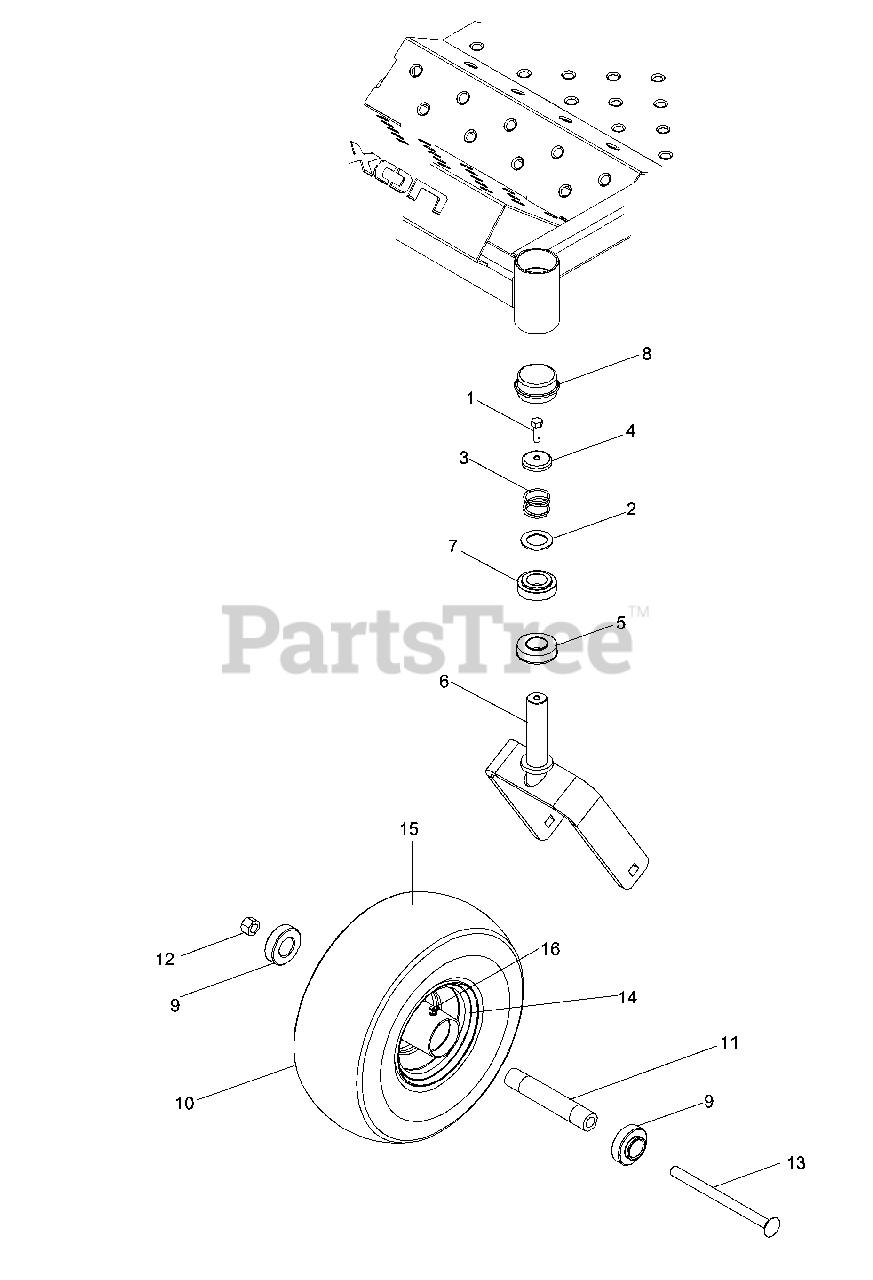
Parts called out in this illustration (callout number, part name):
1	5/16-18X1 HHB G5W/NY
2	WASHER, 1.025 ID X 1.64
3	SPRING, CASTER
4	CASTER.PLUG
5	BEARING
6	CASTER WLDT.
7	BUSHING, CASTER
8	GREASE CAP
9	BEARING-ECC LOCK
10	13-5 X 6 TIRE ASM.-SM
12	NUT, HEX 1/2-13 W/NYLOK
13	1/2-13 X 7 CARR. BOLT
14	WHEEL (REF.13985)
15	TIRE (REF.13985)
16	ZERK, 3/16, DRIVE IN
